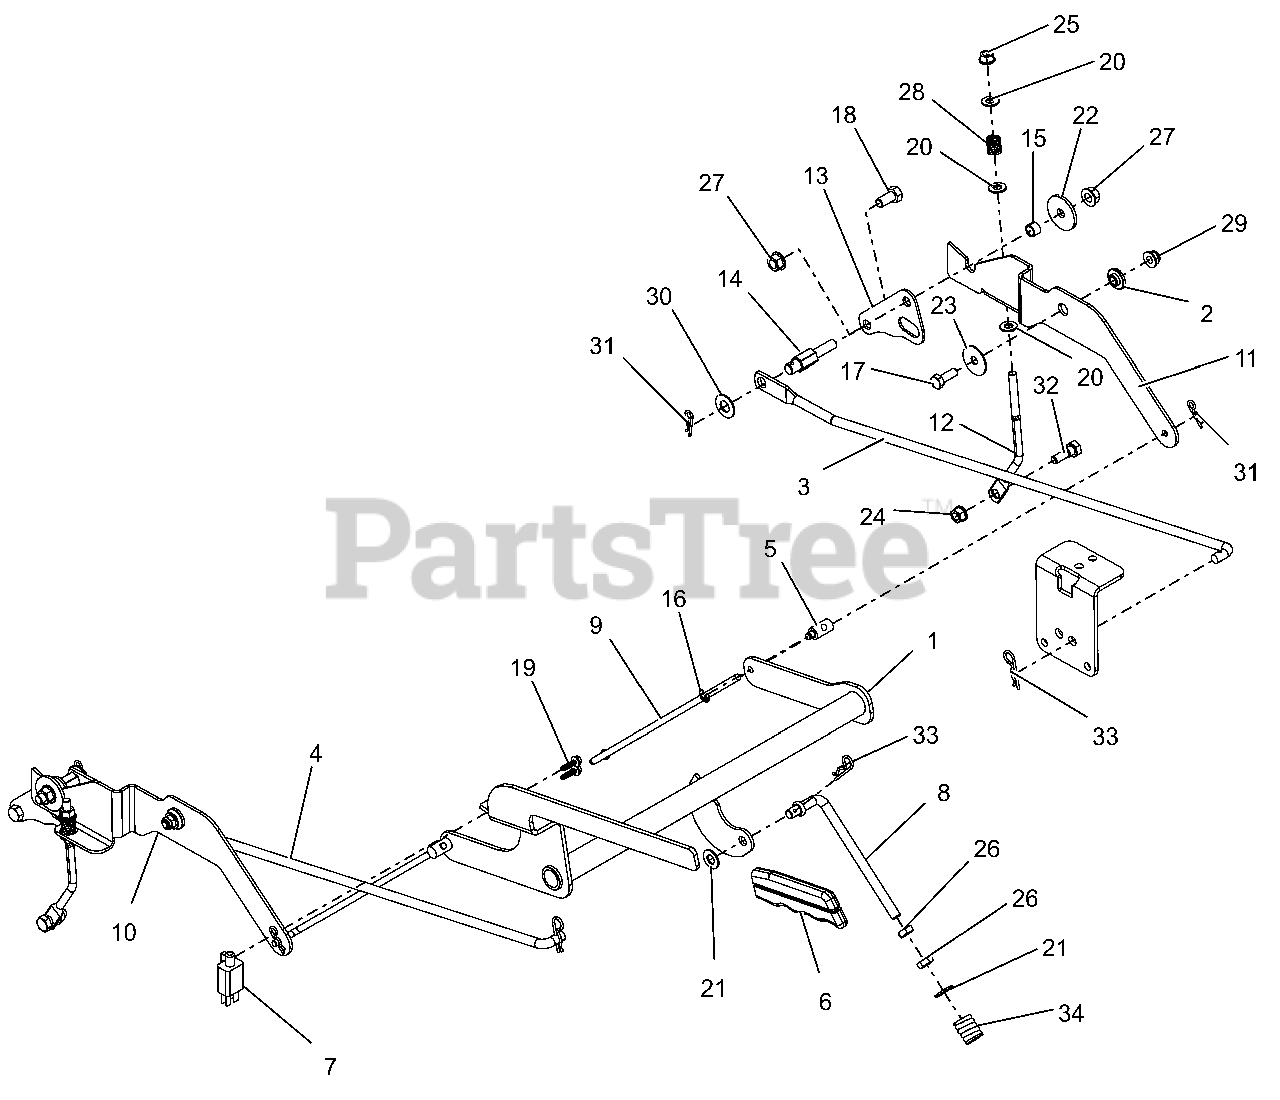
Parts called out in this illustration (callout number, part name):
1	WLDMT, BRAKE LEVER
2	BSHG, FLG .325X.499X.26X.88
3	ROD, STEERING LINKAGE LH
4	LINKAGE, STEERING - RH
5	TRUNION, 1/4-20
6	GRIP, PARKING BRAKE (YELLOW)
7	SWITCH- DOUBLE POLE N.O./N.O.
8	LINK, OVER CENTER, PARKING BRK
9	ROD, PARK BRAKE
10	INTERLOCK, RH BRAKE LINK
11	INTERLOCK, LH BRAKE LINK
12	LINK, BRAKE (XL)
13	PLATE, TRANSAXLE ADAPTOR
14	POST, STEERING LINK MOUNTING
15	SPCR, SLV .385X.500X.350
16	RG-RTNG-EXT .250X.025
17	BLT, HEX .31-18X.875 G5 ZCC
18	BLT,HEX .38-16X.75 G5 ZCC
19	SCR, PLASTITE-HWH 0.2 X 0.75 ZC120
20	WSHR,FLT .344X.688X.065 ZCC
21	WSHR,FLT .406X.812X.065 ZCC
22	WSHR, FLT .380X1.50X.125 ZCC
23	WSHR, FLT .347X1.254X.048 ZCC
24	NUT-LK-TOP-FLG .312-18 GF ZCC
25	NUT,LK-CTR-FLG .31-18 GF ZCC
26	NUT-JAM .375-16 G2 ZCC
27	NUT-LK-CTR-FLG .375-16 GF ZCC
28	SPRING, COMPRESSION
29	NUT,NYL-FLG .31-18 GF ZCC
30	WSHR, FLT .505X1.00X.062 ZCC
31	PIN, HAIR #213 .08X1.19 ZCC
32	BOLT,SHLDR .38X.25 -.31-18X.75
33	PIN, HAIR .09 X 1.50 ZCC
34	SG-COMP .187X.56X1.62
